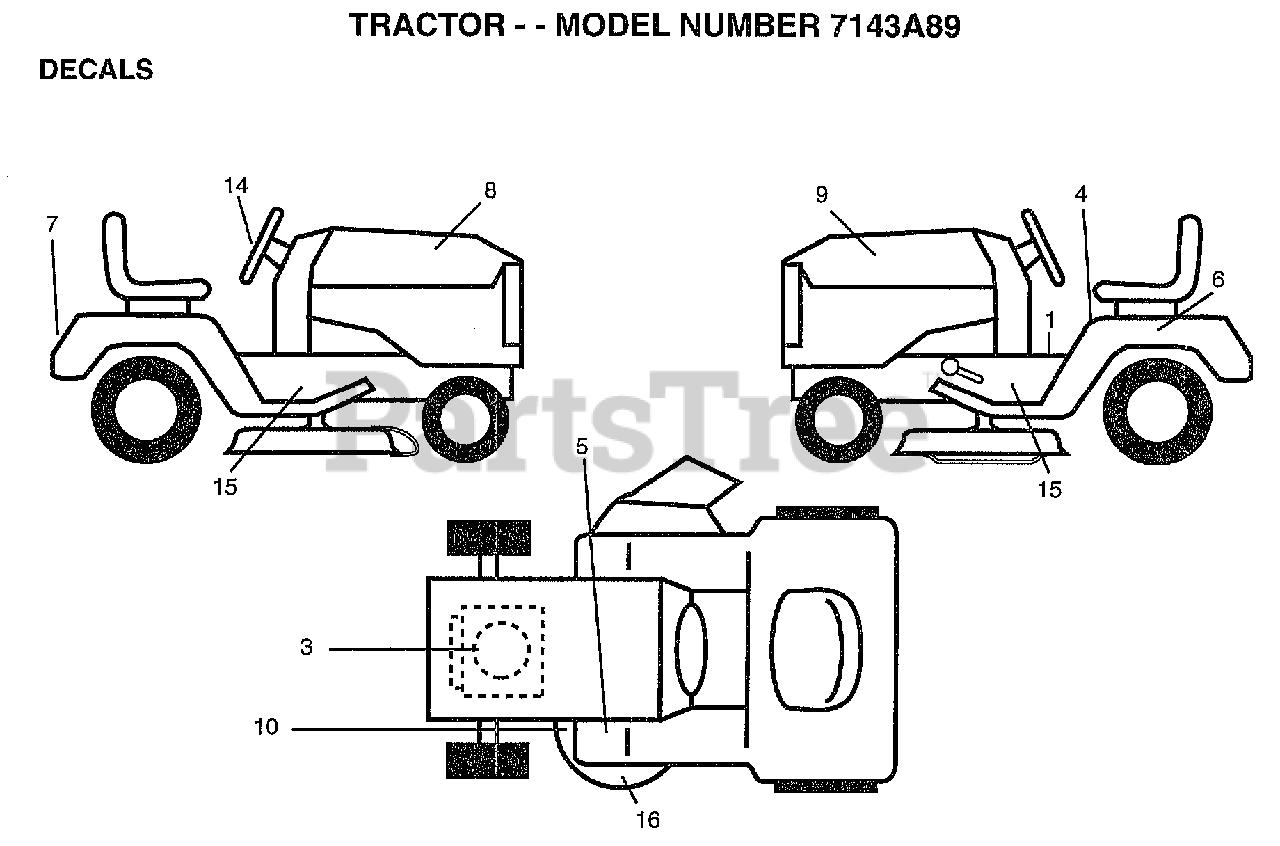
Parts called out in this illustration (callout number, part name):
1	"DECAL DASH,OPER."
3	DECAL, ENGINE
4	"DECAL DANGER,FEND"
6	DECAL.BATRY.3-3908
8	DECAL.HOOD.RH
9	DECAL.HOOD.LH
10	"DECAL-SCHEM,BELT"
14	DECAL.INS.STRG.WL
15	DECAL CHASSIS WIZ
16	DECAL DECK WIZ +
